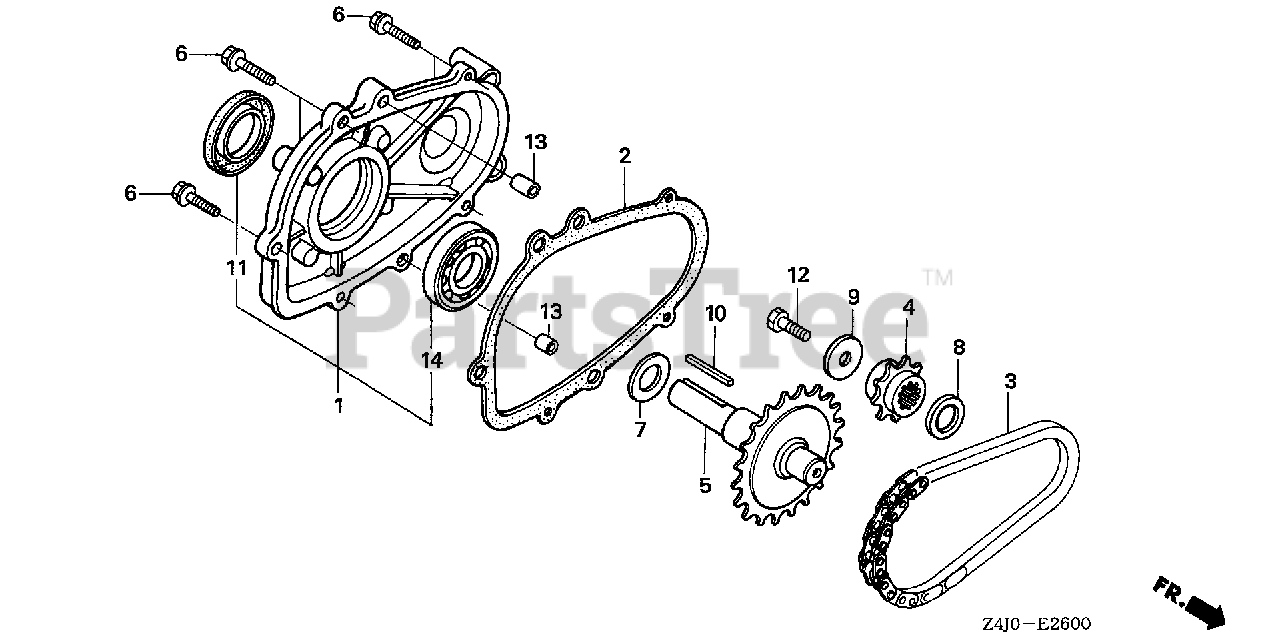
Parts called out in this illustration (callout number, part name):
1	COVER ASSY., CHAIN CASE
2	GASKET, CHAIN CASE COVER
3	CHAIN, P.T.O. DRIVE (DID317FM2-34LE)
4	SPROCKET, DRIVE (13T)
5	SHAFT, P.T.O. (26T)
6	BOLT, FLANGE (6X28) (CT200)
7	SPRING, THRUST
8	SPACER (20MM)
9	WASHER (8MM)
10	KEY (5X5X33) (YELLOW)
11	OIL SEAL (25X41X6) (NOK)
12	BOLT, HEX. (8X25)
13	PIN, DOWEL (8X14)
14	BEARING, RADIAL BALL (6205)
